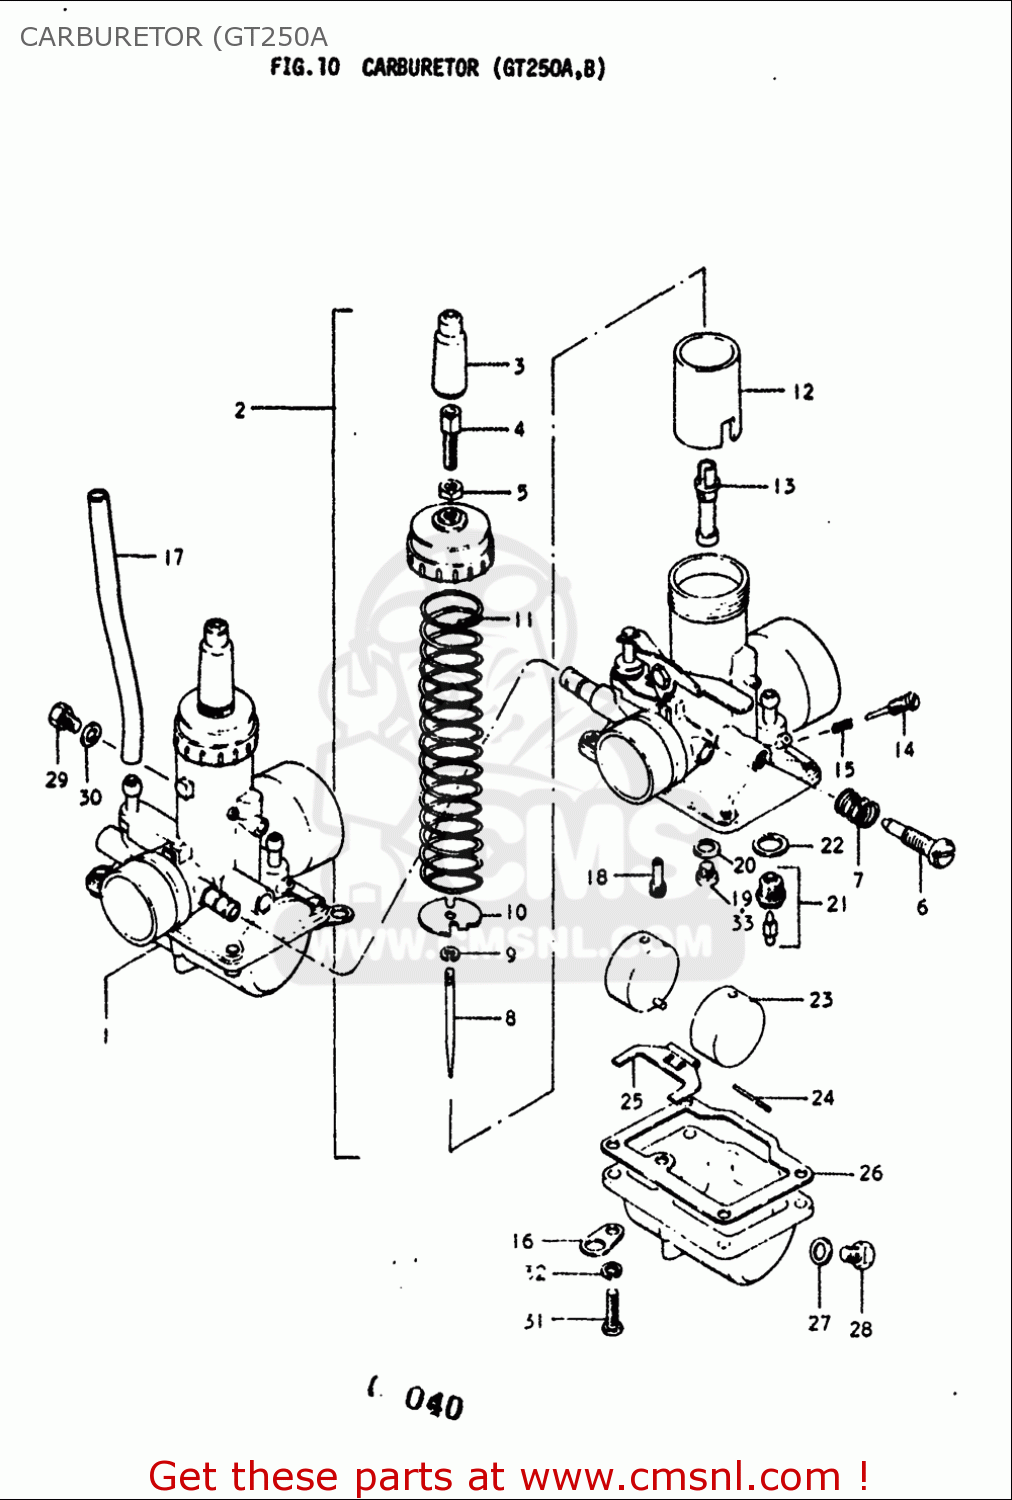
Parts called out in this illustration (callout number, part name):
3	CAP,CABLE ADJUSTER
4	ADJUSTER,CABLE
5	NUT
7	SPRING,THROTTLE SCREW
8	NEEDLE,JET(5CN3)
9	CLIP
13	JET,NEEDLE
14	SCREW,PILOT AIR
15	SPRING
16	PLATE
17	HOSE(4.5X8.5X600)
18	JET,PILOT(30)
19	JET,MAIN(95)
20	WASHER
21	VALVE ASSY,NEEDLE
22	GASKET,VALVE SEAT (NAS)
23	FLOAT
24	PIN,FLOAT
26	GASKET,FLOAT CAHMBER (NAS)
27	GASKET,DRAIN,PLUG (NAS)
28	PLUG
29	BOLT
30	GASKET,THRO VALVE INSPECTION (NAS)
31	SCREW 4X16
32	WASHER,LOCK
33	JET,MAIN
